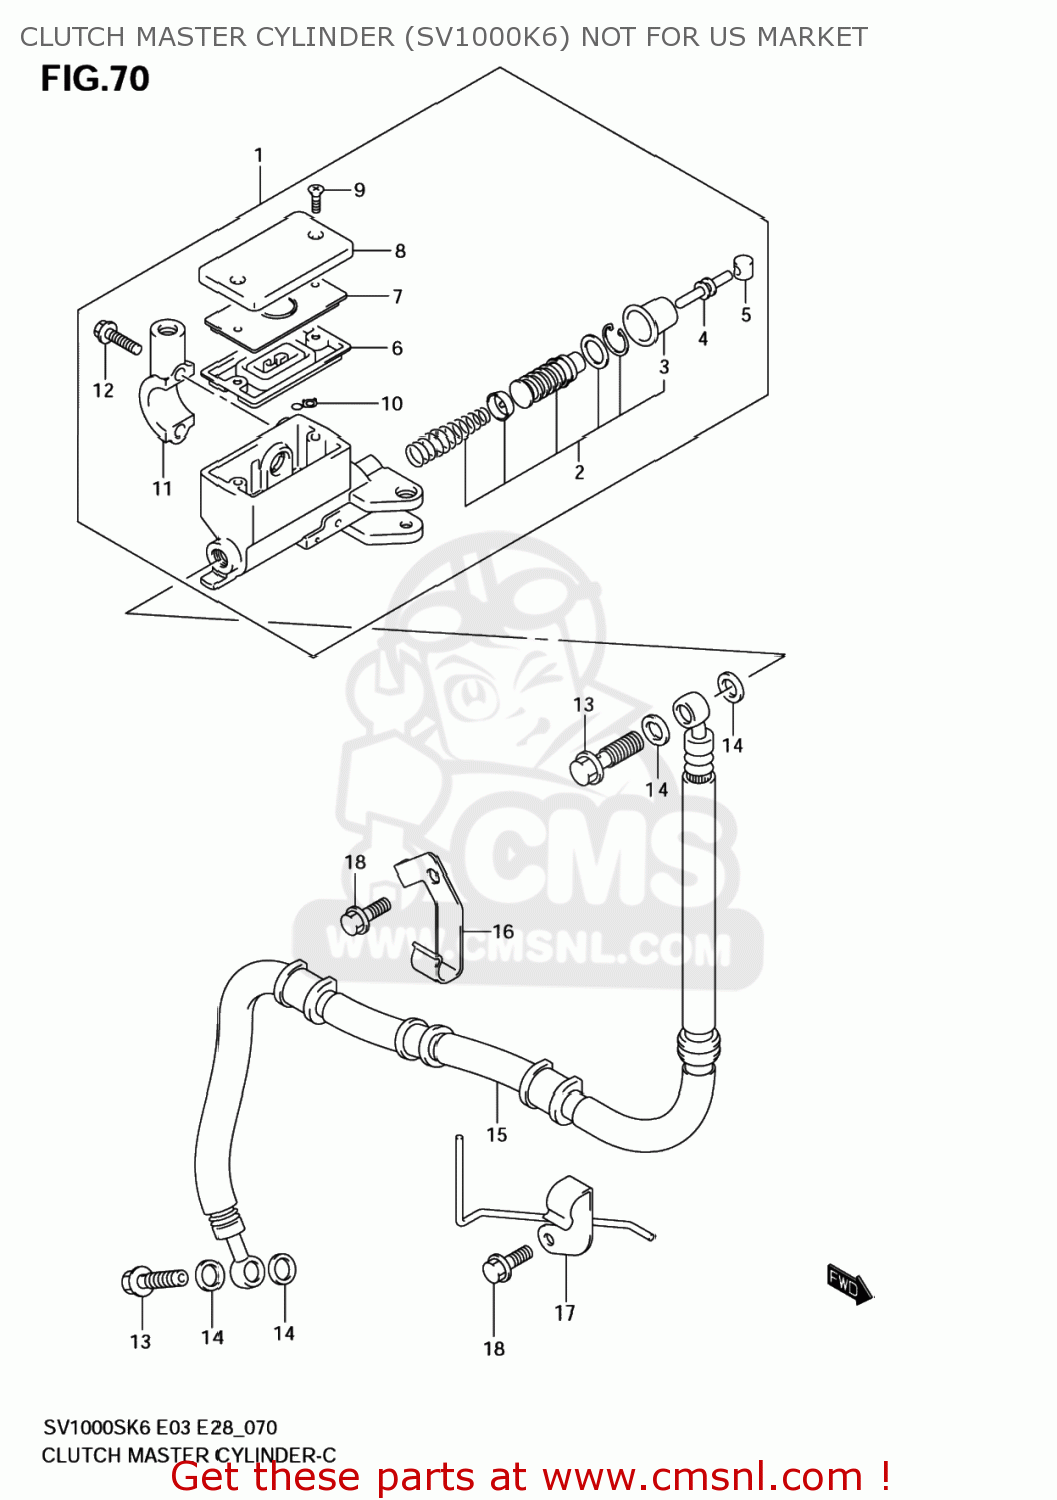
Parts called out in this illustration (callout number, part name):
1	CYLINDER ASSY,
2	PISTON & CUP SET
3	BOOT
4	PUSH ROD
5	BUSH
6	7
7	PLATE,DIAPHRAGM
8	CAP
9	SCREW
10	PROTECTOR
11	HOLDER
12	BOLT(6X22)
13	BOLT UNION
14	WASHER(10X15X1.5)
15	HOSE,CLUTCH
16	CLAMP,CLUTCH HOSE NO.2
17	CLAMP,CLUTCH HOSE
18	BOLT
